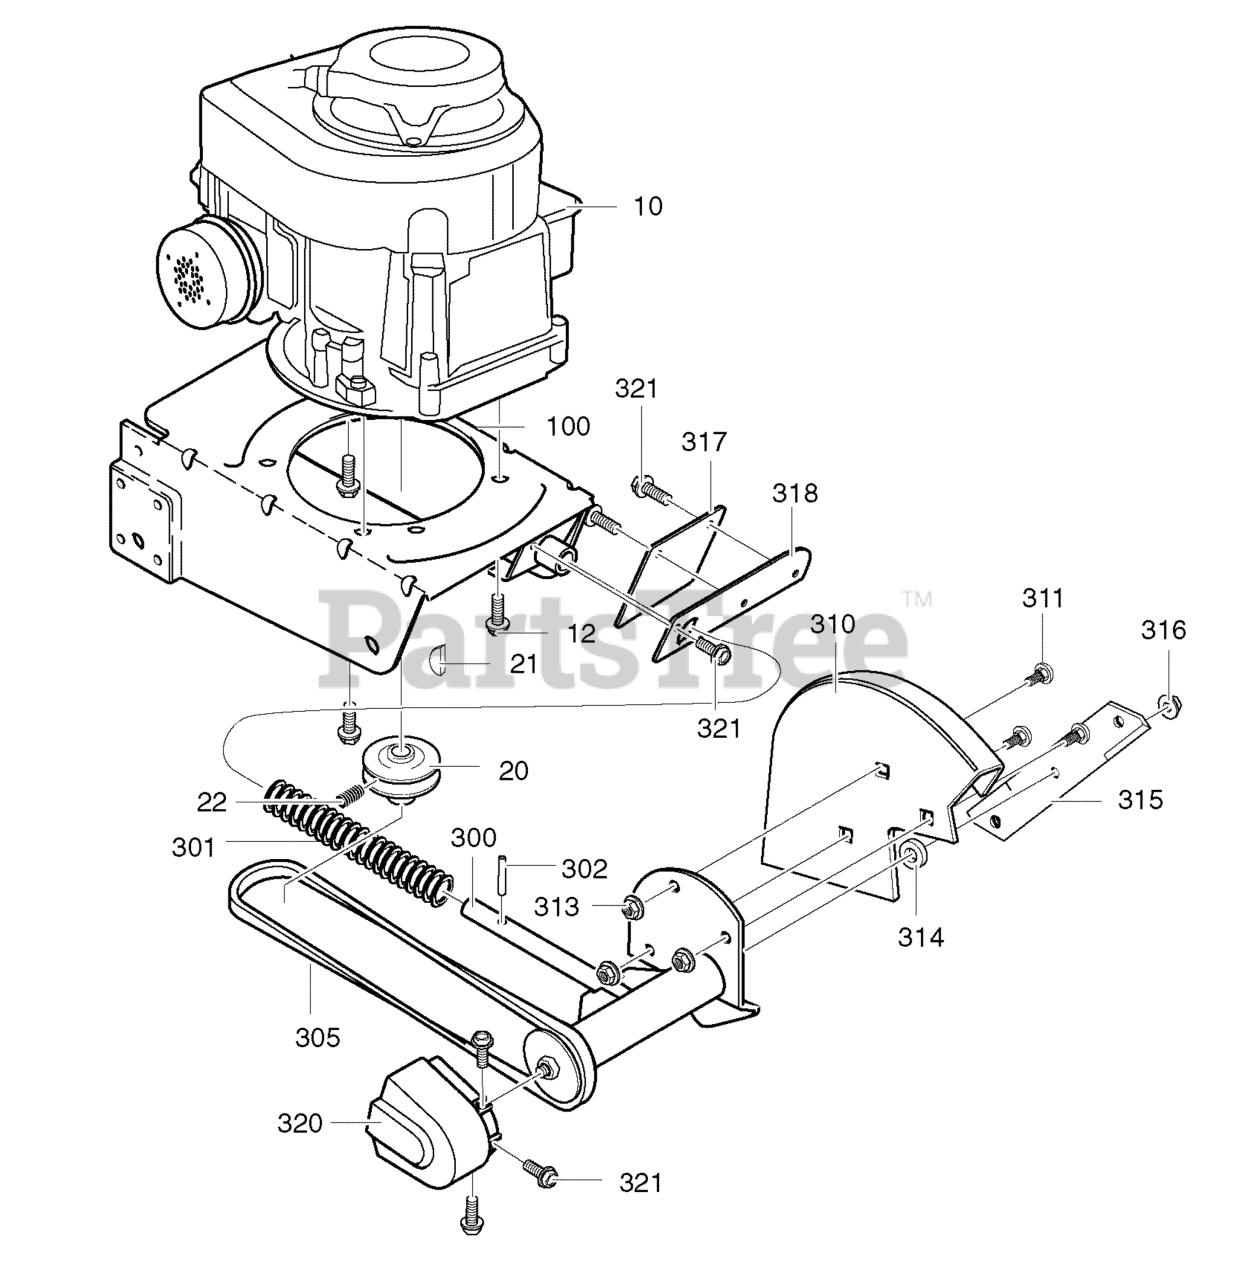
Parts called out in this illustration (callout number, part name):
10	ENGINE 3.5 HP
20	PULLEY, V3L
21	KEY, Hi Pro #505
22	SCREW, Set
100	FRAME, Edger
300	QUILL ASSEMBLY
302	SPRING PIN
305	BELT, V4L
310	BLADE GUARD
311	BOLT, Carriage
313	NUT, 5/16-18
314	WASHER, Flat
315	BLADE, Edger
316	NUT, 1/2-20
317	DEFLECTOR, Rubber
318	PLATE, Rubber Flap
320	BELT GUARD
321	SCREW, 10-16x.50
